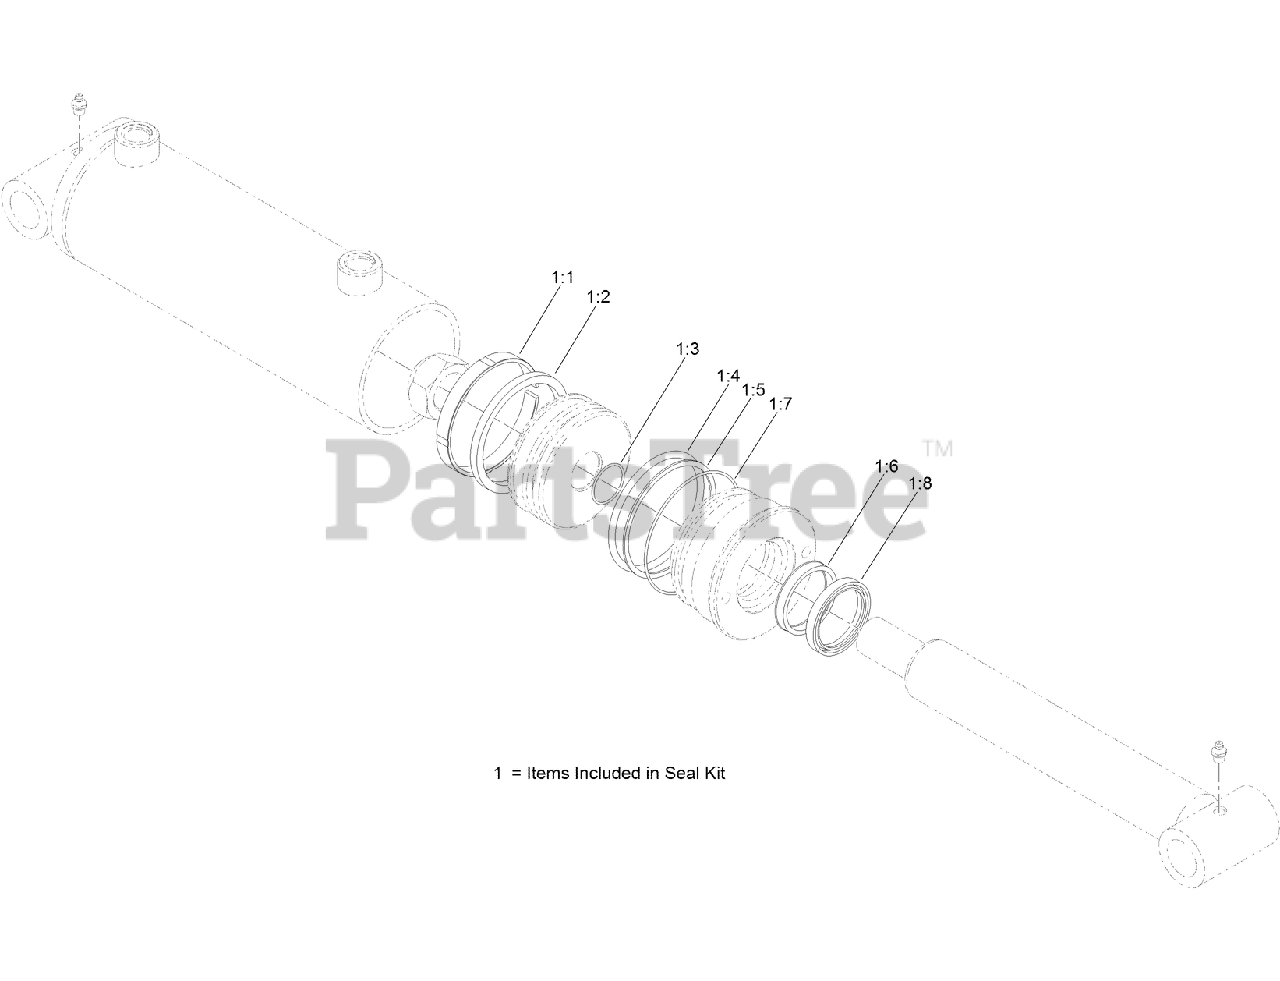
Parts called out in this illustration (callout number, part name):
1:1	RING-BEARING
1:2	TEFLON SEAL ASM
1:3	O-Ring
1:4	O-Ring
1:5	Washer-Backup
1:6	Cup-U
1:7	O-Ring
1:8	Wiper
